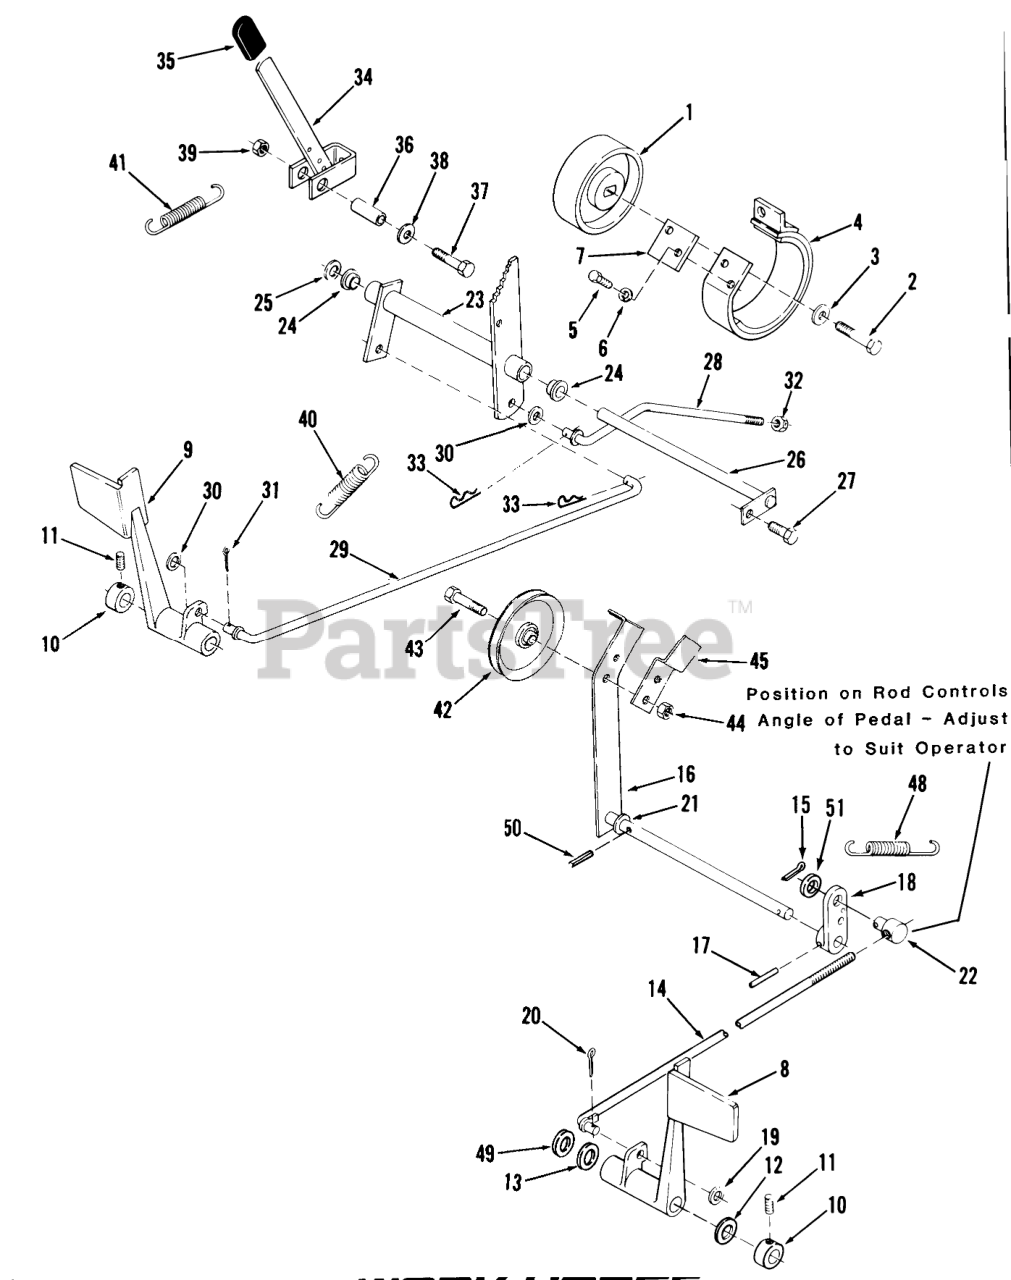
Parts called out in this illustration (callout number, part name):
1	DRUM-BRAKE
2	SCREW-HEX HD CAP
3	WASHER
4	BRAKE BAND ASM
5	H H C S
6	Washer
7	Plate-Stop
8	Clutch Pedal
9	PEDAL-BRAKE R
10	Collar
11	SCREW-SET
12	WASHER-BOWED
13	WASHER
14	ROD AND GUIDE ASM
15	Cotter Pin
16	Clutch Idler Arm
17	PIN-SPIROL
18	Arm-Clutch Rod
19	WASHER-NYLON
20	Pop Rivet
21	SHIM-WASHER
22	TRUNNION
23	Bellcrank Assy
24	BUSHING-FLANGED
25	Washer
26	ROD ASM
27	SCREW
28	ROD-REAR BRAKE
30	WASHER-NYLON
31	Pop Rivet
32	NUT
33	Hairpin
34	ASSY-BRAKE LEVER WAB
35	GRIP
36	SPACER
37	Bolt 3/8-16 x 1 3/4
38	Washer
39	LOCKNUT-FLANGE
40	SPRING-BRAKE
41	SPRING-EXTENSION
42	PULLEY-IDLER
43	BOLT-SPECIAL HEX
44	Nut
45	ACTUATOR-SWITCH R
48	SPRING-CLUTCH
49	Washer
50	PIN-SPIROL
51	Washer
